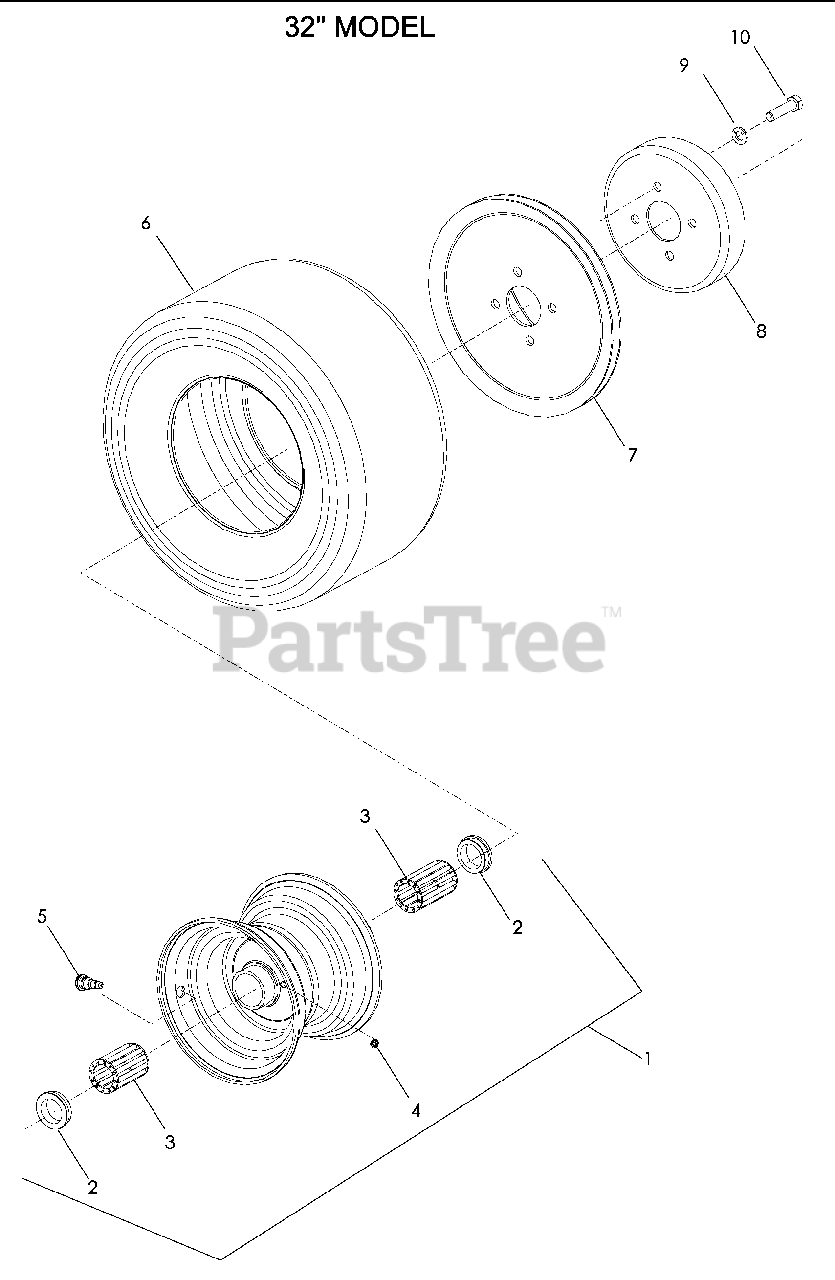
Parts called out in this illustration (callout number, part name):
1	WHEEL ASSM
3	ROLLER BEARING
4	ZERK ¼-28 STRAIGHT
7	TRACTION PULLEY
8	BRAKE DRUM
9	LOCKWASHER 3/8
10	HCS 3/8-24 x ¾
